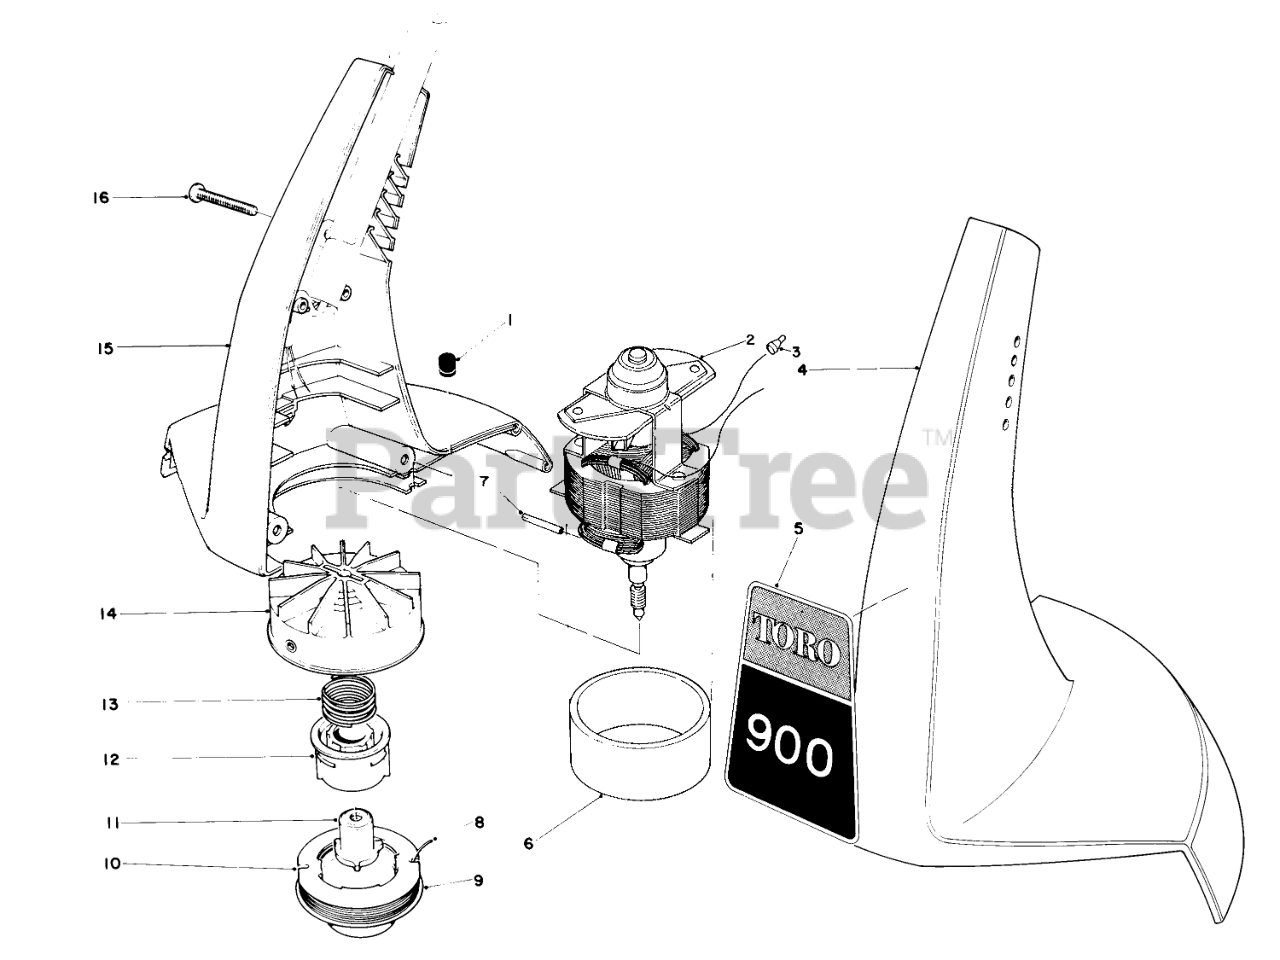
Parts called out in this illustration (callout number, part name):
1	GROMMET
2	CONNECTOR WIRE JOINT
3	Motor (240 V)
4	Left Housing
5	Decal-900 Toro
6	DAMPENING SLEEVE
7	COIL PIN
8	.040" Cutting Line in Coil
9	SPOOL CAP
10	Prewound Spool
11	DRIVER DETENT
12	CORE - SPOOL
13	SPRING-COMPRESSION
14	FAN HUB ASM
15	Right Housing
